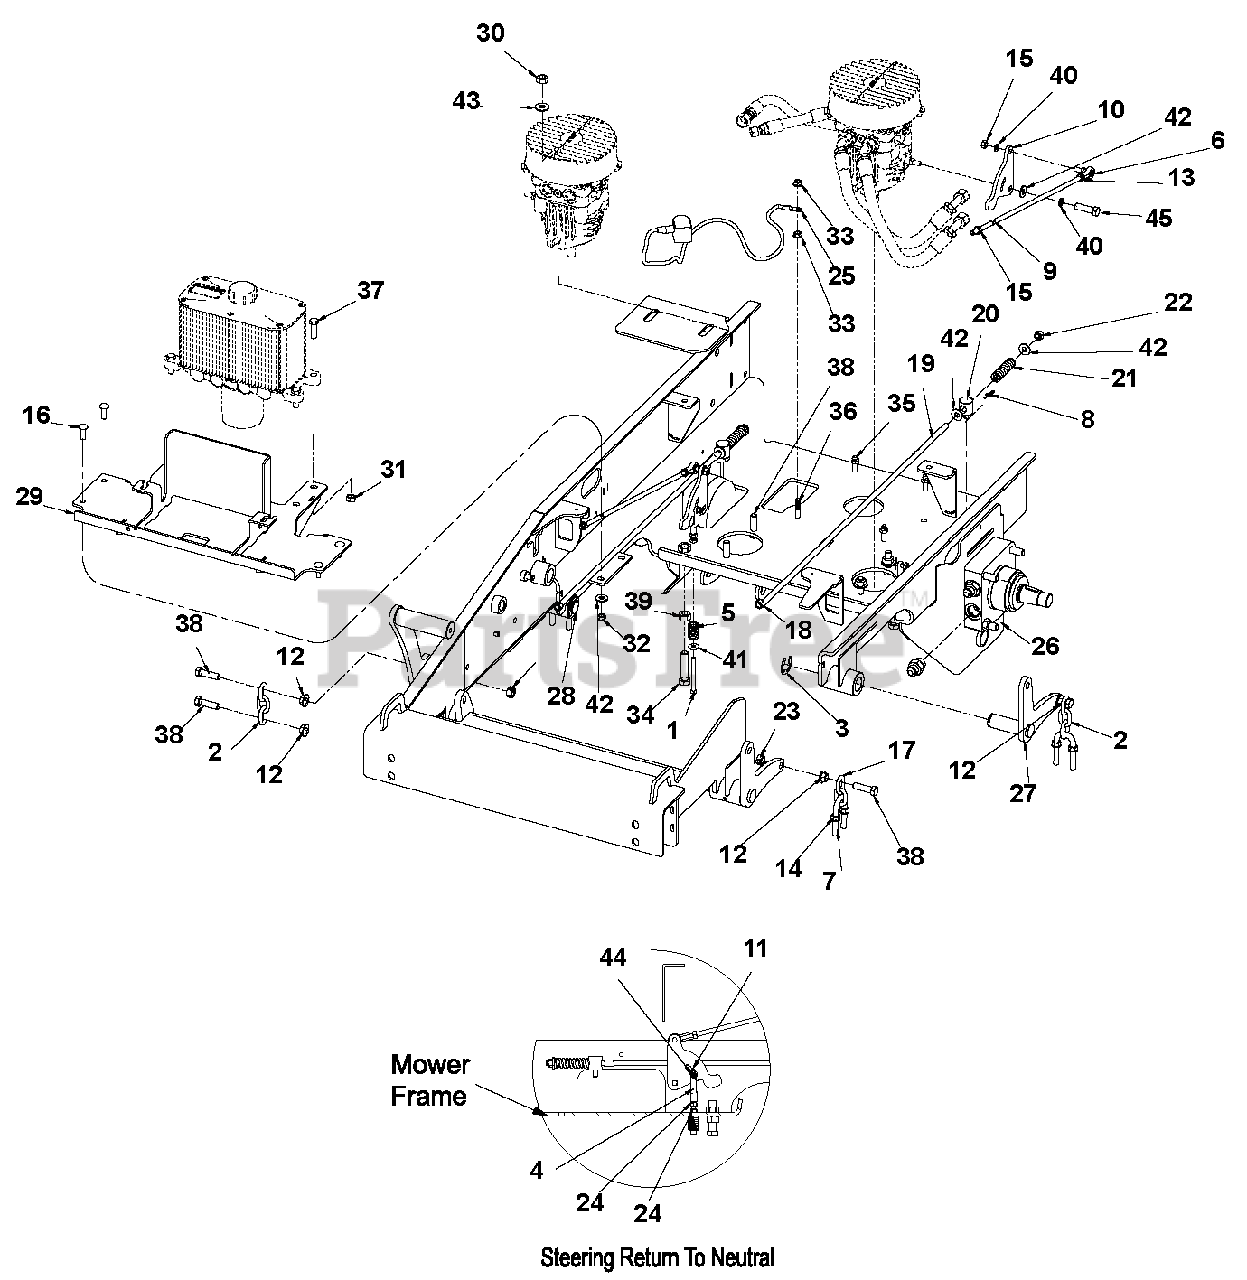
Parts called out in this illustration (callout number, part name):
1	Bolt, 1/4-20 x 2.75 SOC 8
2	Chain - 3 Links
3	E-Ring, 1.00 x .050
4	Yoke, 1/4-20 RH Adjustable
5	Spring, Compression .784 x .092 x 1.50
6	Ball Joint, LH 5/16 FMAL W/STD
7	U-Bolt, RD 1.00 x 2.50 x 3/8-16
8	Ring, Rue .375 x .054 x 1.254
9	Rod, Pump Control
10	Plate, Pump Control Arm
11	Ring, Rue .250 x .041 x .844
12	Locknut, 7/16-14 Whiz
13	Nut, 5/16-24 Hex Grade 5 LH
14	Locknut, 3/8-16 Whiz
15	Nut, 5/16-24 STD Hex Grade 5
16	Bolt, 5/16-18 x 1.00 CRG 2
17	Chain, 2 Links 1/4"
18	Nut, 3/8-24 STD Hex Grade 5
19	Rod, Brake
20	Pin, Brake Linkage
21	Spring, Compression .710 x .142 x 2.50
22	Locknut, 3/8-24 Crown
23	Locknut, 7/16-14 Center
24	Locknut, 1/4-20 Nyloc
25	Cable, Battery - 35" Ground
26	Weldment, Wheel Motor Plate
27	Weldment, LH Front Deck Lift
28	Weldment, RH Front Deck Lift
29	Weldment, Battery/Tank Plate
30	Locknut, 7/16-14 Crown
31	Locknut, 3/8-16 Crown
32	Locknut, 5/16-18 Crown
33	Locknut, 5/16-18 Whiz
34	Bolt, 1/2-13 x 2 3/4 Grade 2
35	Bolt, 5/16-18 x 1.50 Hex Grade 5
36	Bolt, 5/16-18 x 1.75 Hex Grade 5
37	Bolt, 3/8-16 x 1.25 Hex Grade 5
38	Bolt, 7/16-14 x 1.50 Hex Grade 5
39	Nut, 1/2-13 STD Hex Grade 5
40	Washer, .313 Med Spring Lock
41	Washer, .250 Reg Flat
42	Washer, .313 Reg Flat
43	Washer, .375 Reg Flat
44	Pin, CVS .250 x 1.00 x .859
45	Bolt, M8 x 1.25 x 20 He 8.8"
